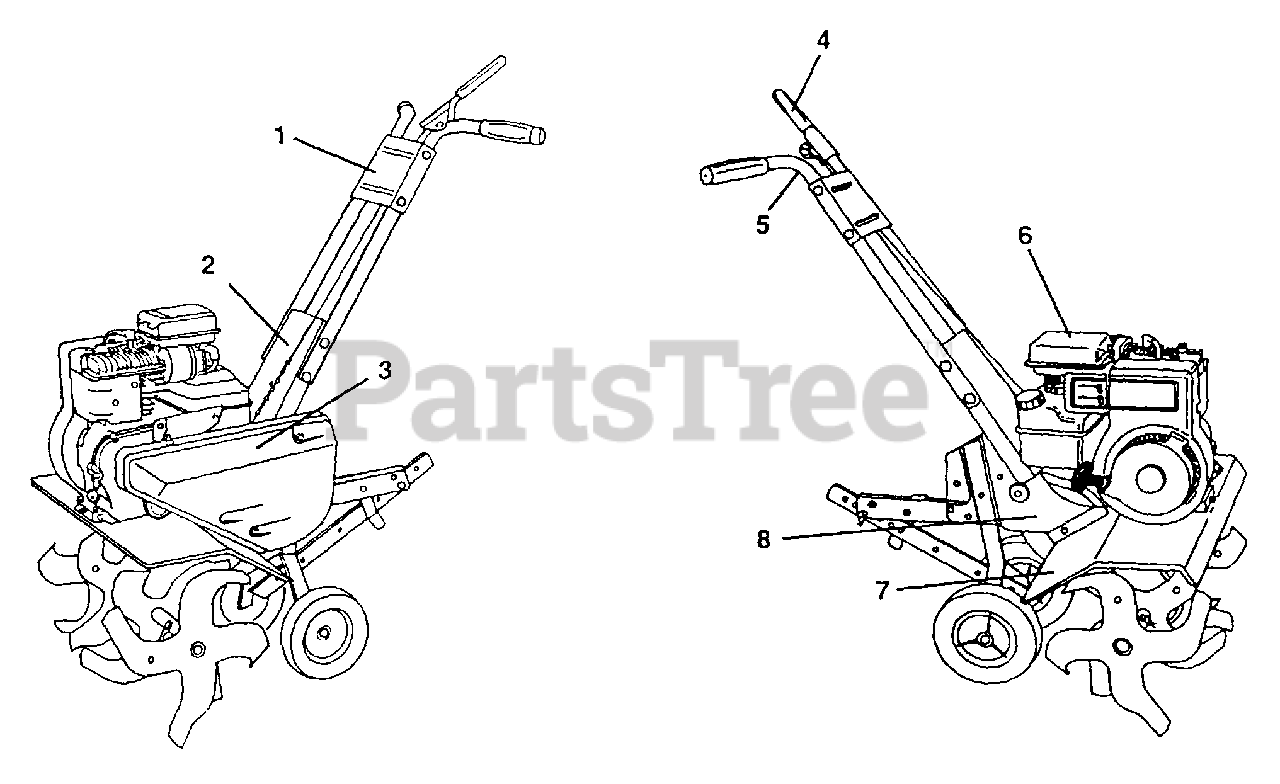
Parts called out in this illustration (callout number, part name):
1	Decal, Logo
2	Decal, HP
3	Decal, Logo
4	Decal, Tine Control (AYP part number)
5	Decal, Hand Placement (AYP part number)
6	Decal, Caution (AYP part number)
7	Decal, Warning, Rotating Tines (AYP part number)
8	Decal, Cust Assist
